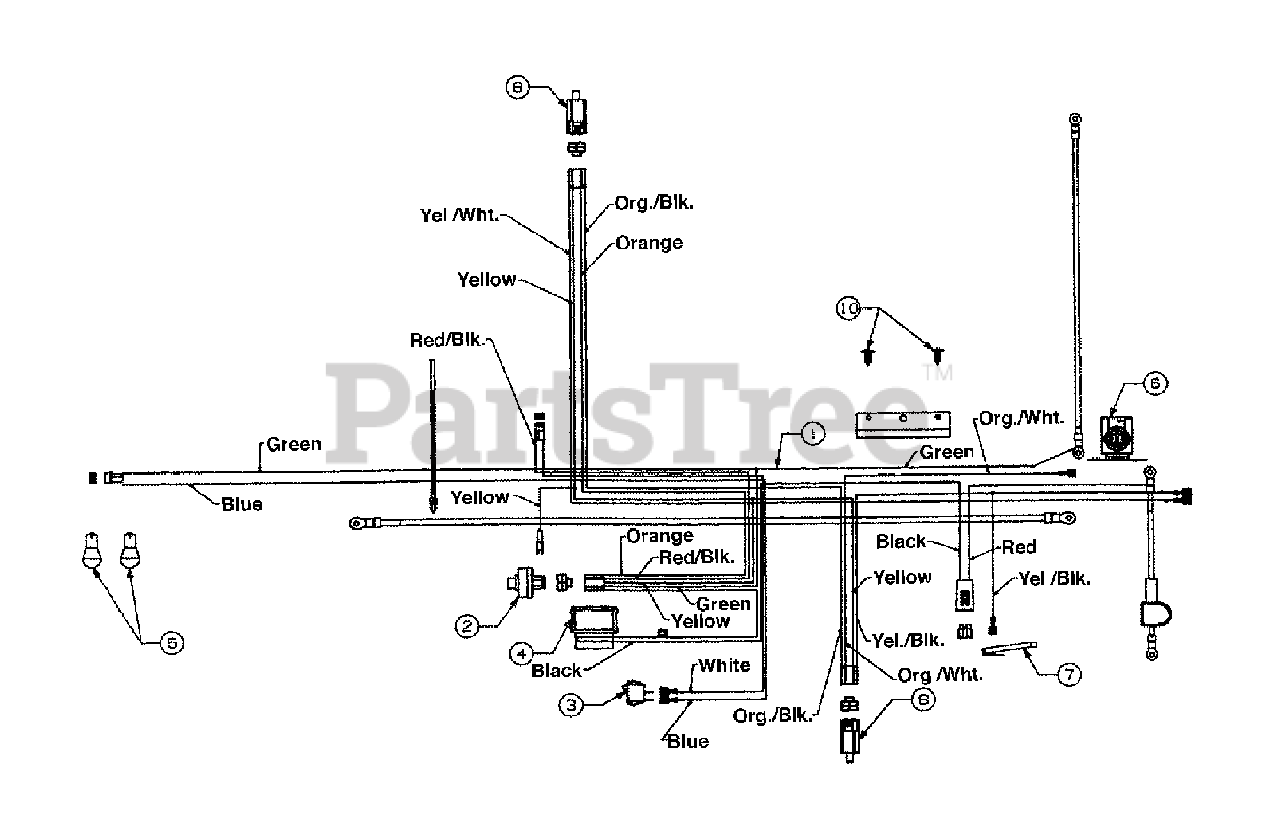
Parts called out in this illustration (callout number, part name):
1	Wire Harness w/Light Switch & Amp
2	Ignition Switch
3	Light Switch
4	Ammeter
5	Bulb
6	Solenoid
7	Safety Switch
8	Safety Switch
10	Ratchet
